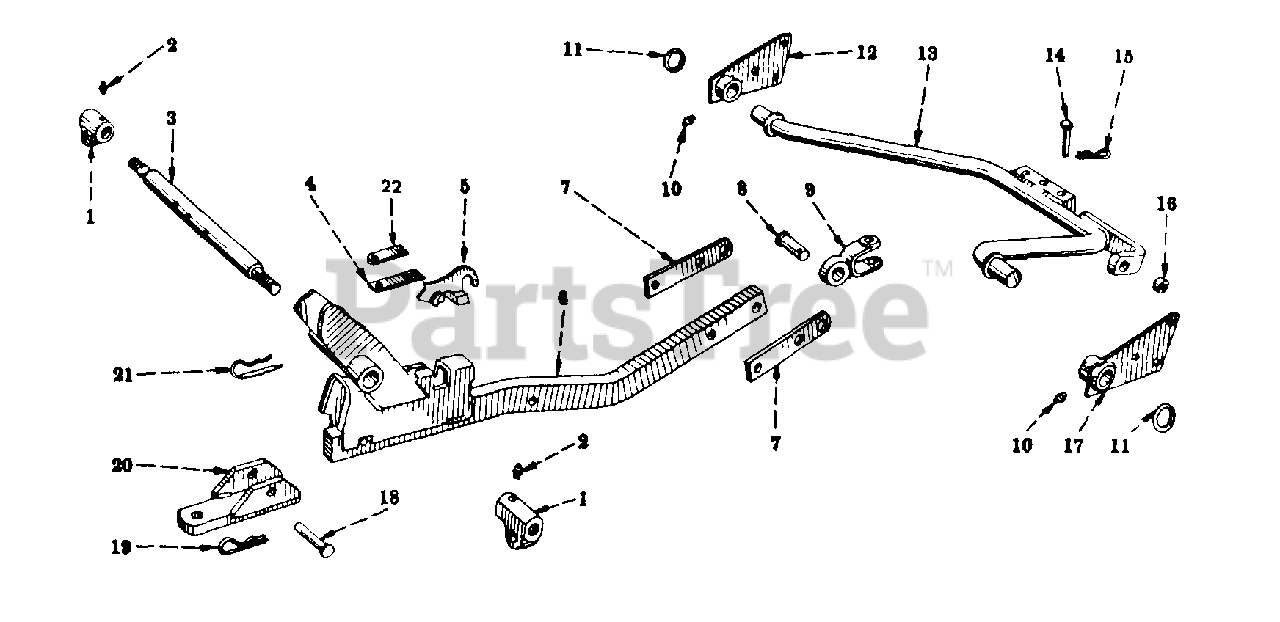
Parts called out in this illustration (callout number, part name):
1	SWIVEL, LATERAL LINK LOWER
2	FITTING, 1/8-27 STR LUB
3	SUPPORT, PULL BAR
4	SPRING, LATCH
5	LATCH, PULL BAR
6	BAR ASSY, PULL
7	STRAP, PULL BAR EXTENSION
8	PIN, PULL BAR PIVOT
9	BRACKET, PULL BAR PIVOT
10	FITTING, 1/8-27 STR LUB
11	WASHER, 1-13/32 X 2-1/8 X 11 GA
12	PLATE ASSY, ATTACHING HITCH LH
13	BAIL ASSY, HITCH
14	PIN, PULL BAR PIVOT BRACKET
15	PIN, 3/16 QUICK-ATTACHABLE COT.
16	BUSHING, SCREW CLEVIS
17	PLATE ASSY, ATTACHING HITCH RH
18	PIN, 5/8 X 3-5/16 STD-HD DRILLED
19	PIN, 3/16 QUICK-ATTACHABLE COT.
20	EXTENSION, PULL BAR
21	PIN ASSY, QUICK-ATTACHABLE COT.
22	SPRING, AUXILIARY LATCH
